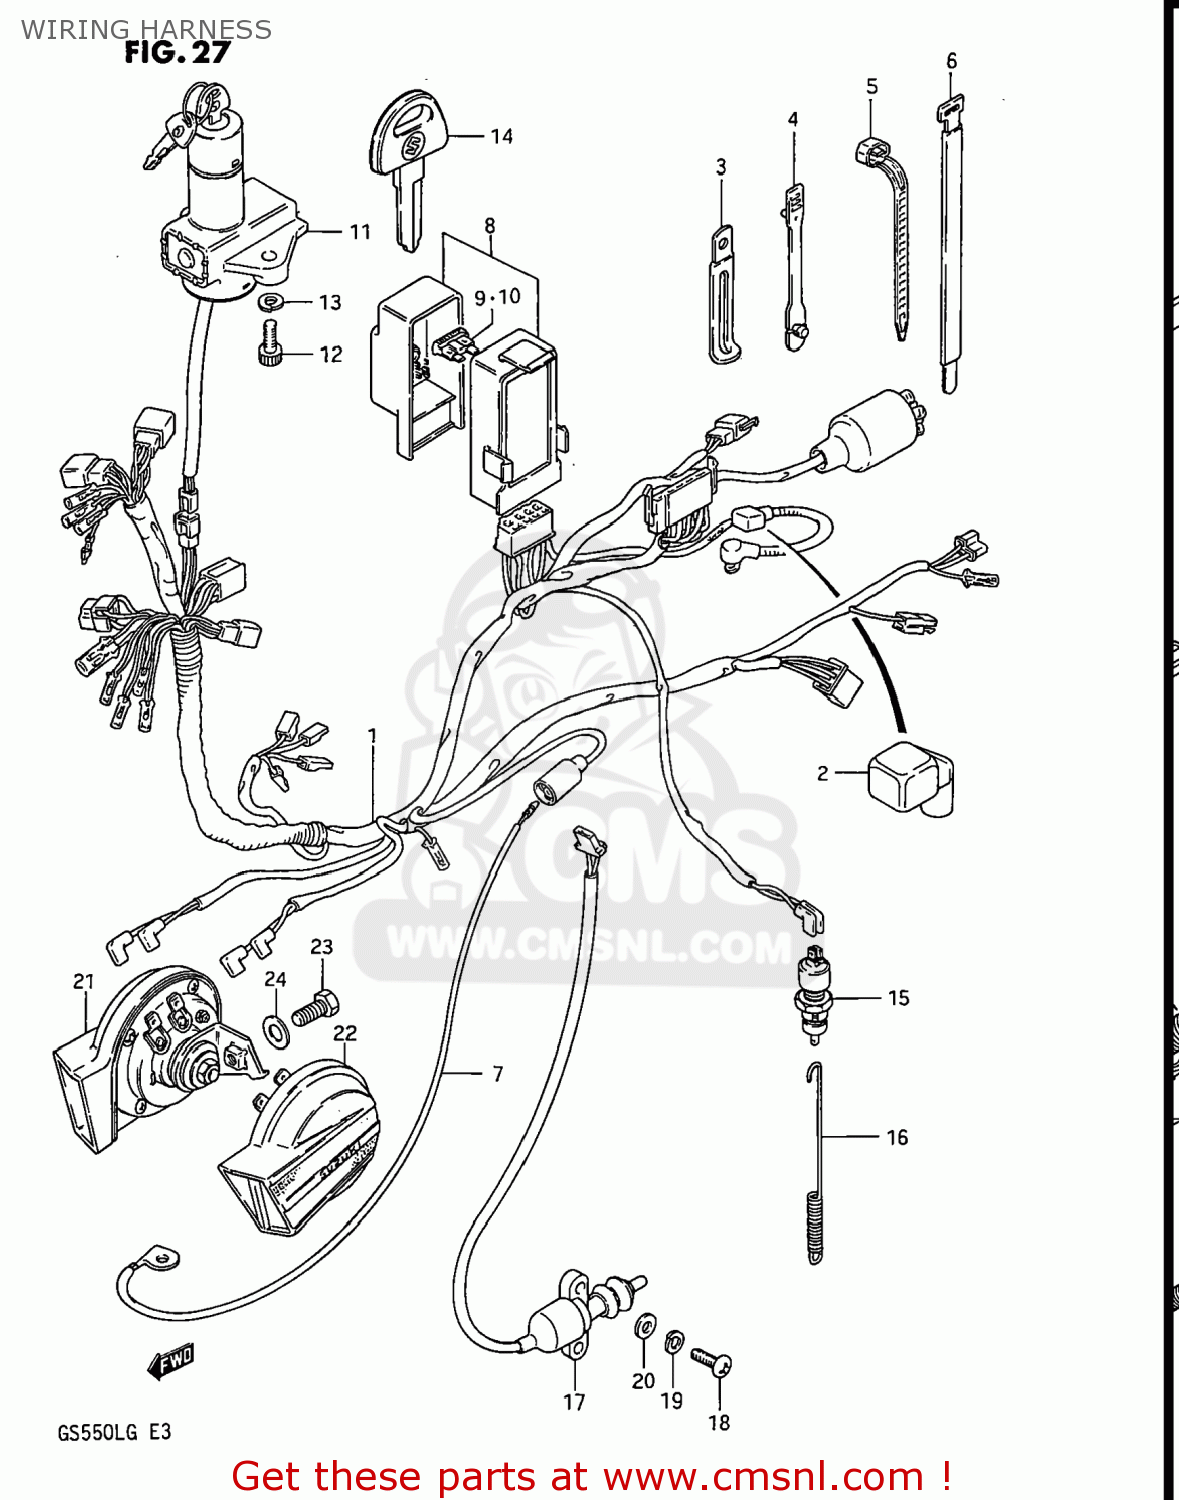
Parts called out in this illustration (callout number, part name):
1	HARNESS,WIRING
2	CAP,BATTERY PLUS TERMINAL
3	CLAMP
4	CLAMP,L:88
5	CLAMP(L:125)
6	CLAMP
7	WIRE,OIL PRESSURE SWITCH
8	FUSE BOX ASSY
9	FUSE(10A)
10	FUSE(15A)
11	SWITCH ASSY,IGNITION
12	BOLT
13	WASHER,LOCK
14	KEY,BLANK
15	SWITCH ASSEMBLY,STOP LAMP
16	SPRING
17	SWITCH ASSY,SIDE STAND WARNING
18	SCREW 5X20
19	WASHER,LOCK
20	WASHER,5MM
21	HORN ASSEMBLY,HIGH PITCH
22	HORN ASSEMBLY,LOW PITCH
23	BOLT
24	WASHER
